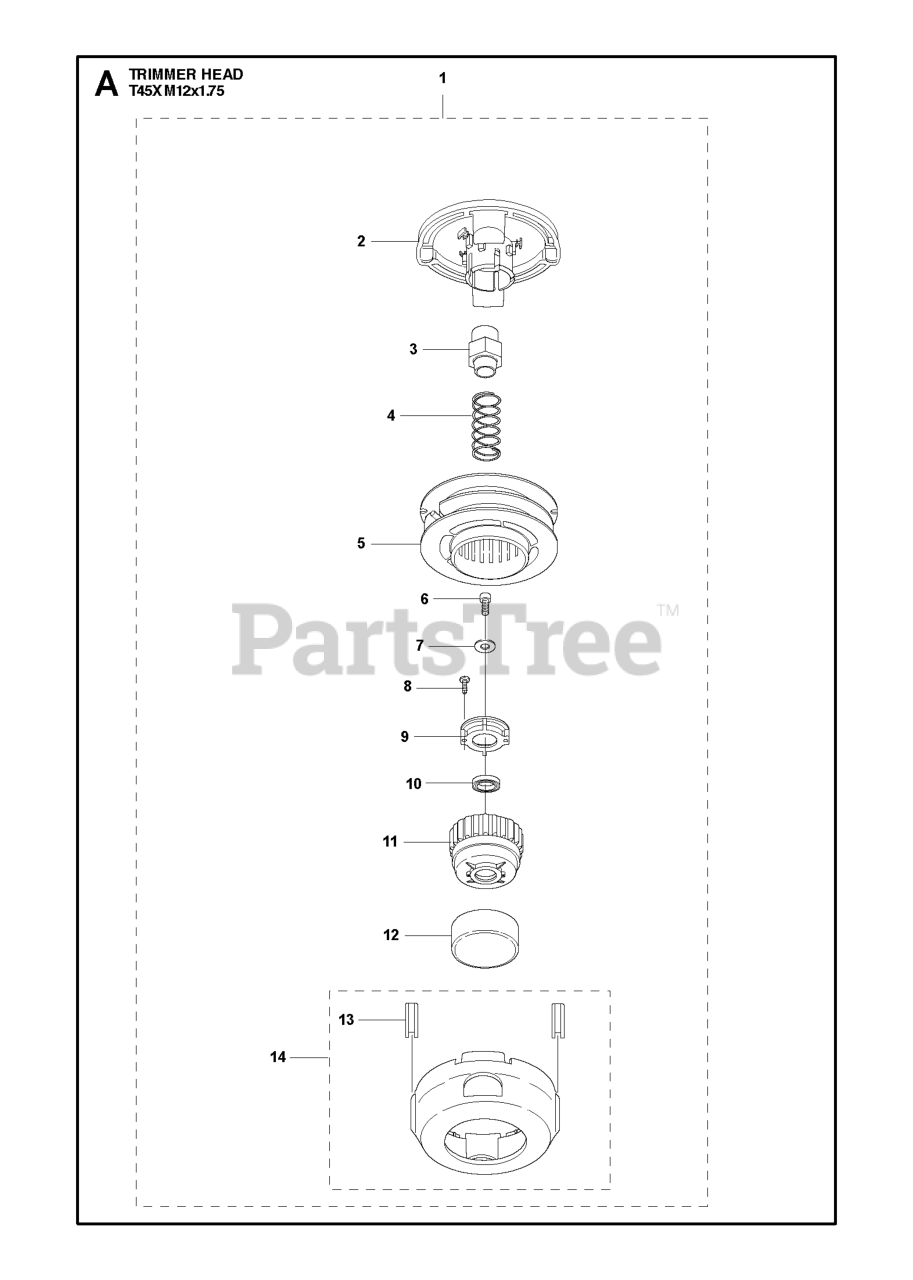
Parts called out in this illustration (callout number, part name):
1	HUS T45X TRIMHEAD 12MM LH
2	UPPER SECTION CAN'T BUY SEPARA
10	BALL BEARING
14	LID SPARE PART ASSY T45
